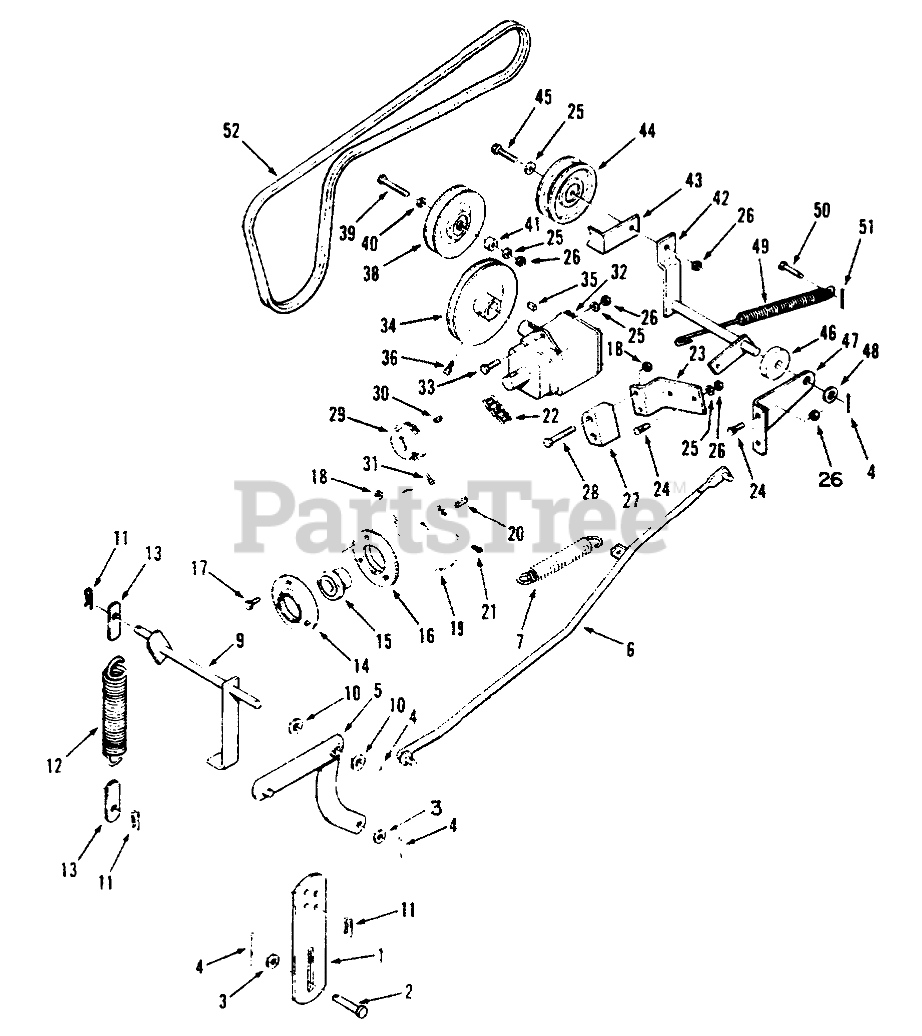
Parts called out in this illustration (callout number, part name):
1	LINK-LIFT R
2	CLEVIS PIN
3	WASHER-FLAT
4	PIN-COTTER
5	WLDMT-SNOWTHWR LI R
6	WLDMT-LIFT ROD R
7	SPRING
9	WLDMT-SPRING SUPP R
10	Washer
11	Hairpin Cotter
12	SPRING
13	RETAINER-SPRING R
14	Flange
15	BEARING AND COLLAR
16	FLANGE-RELUBE
17	BOLT-CARR
18	NUT-LOCK, NI
19	SPROCKET-33T
20	KEY
21	SCREW-SET, SQH
22	CHAIN
23	BRACKET-TIGHTENER R
24	BOLT-CARR
25	WASHER-FLAT
26	NUT-LOCK, NI
27	Chain Tightener
28	SCREW-HH
29	SPROCKET-15 T
30	KEY-HI PRO
31	SCREW-SET
32	GEAR-BOX L.H.
33	BOLT-CARR
34	PULLEY - GEAR BOX
35	KEY-WOODRUFF
36	SCREW-SQH
38	"V" Pulley
39	SCREW-HH
40	WASHER
41	SPACER
42	WLDMT-IDLER ARM R
43	Spacer
44	PULLEY-FLAT IDLER
45	SCREW-HH
46	RUBBER WASHER
47	BRACKET-PIVOT R
48	WASHER-FLAT
49	SPRING
50	PIN-CLEVIS
51	PIN-COTTER
52	V-BELT 64 .5EL
